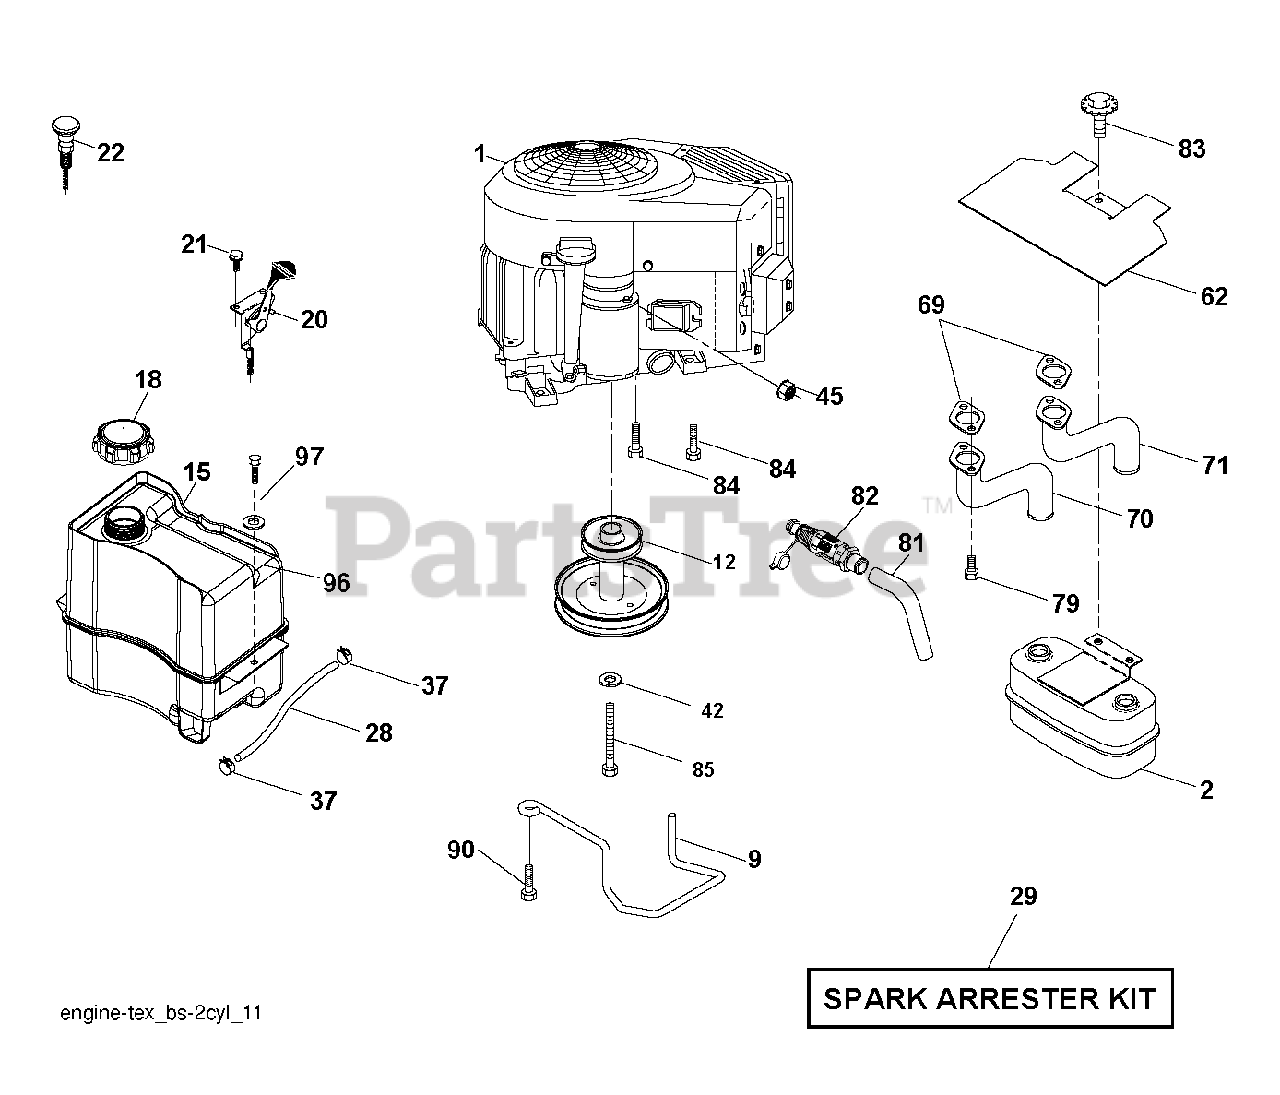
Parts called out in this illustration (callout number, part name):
2	MUFFLER.TWIN.CYL.LOW.TONE
9	KEEPER.BELT.ENGINE.4.2
12	PULLY ENGINE
15	TANK.ASM.FUEL.FR.2.5GA.
18	CAP.FUEL.2.25"VENTED"
20	THROTTLE CABLE
21	SCREW.#10 X 0.750.BOS
22	CONTROL.CHOKE.ERGO.PUSH-IN.BLA
28	LINE.FUEL.20"FRONT.EMI
29	KIT.SPARK ARRESTOR 794945 B&S
37	HOSE CLAMP
42	LOCKWASHER
45	NUT
62	RP SHIELD HEAT MUFFLER
69	GASKET.MUFFLER
70	RP.EXHAUST.TUBE.LH.BS/TWIN
71	EXHAUST.TUBE.RH.BS/TWIN
79	SCREW.SOCKET.HEAD.5/16-18
81	TUBE, DRAIN OIL ASM.
82	VALUE.OIL.DRAIN
83	BOLT, 5/16-18 X 1 3/4
84	SCREW.3/8-16
85	BOLT HEX 7/16-20X4-1/4"
90	SCREW 3/8-16X1
97	SCREW HEXWSHR 1/4-20X3/4
